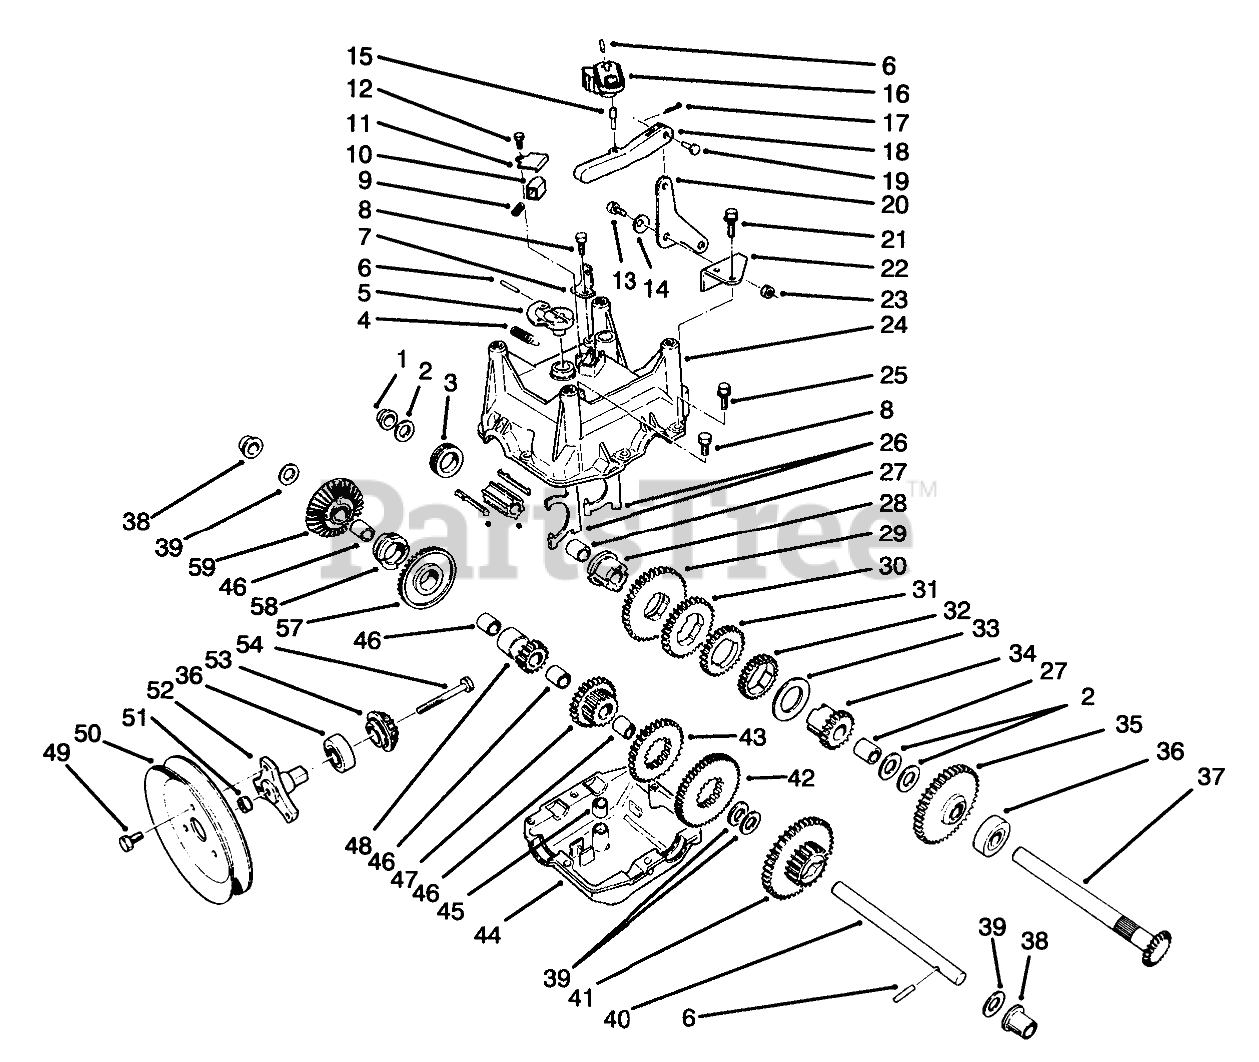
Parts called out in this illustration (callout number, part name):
1	BUSHING-FLANGE, OUTPUT
2	BEARING-THRUST
3	COLLAR-SHIFT
4	SPRING-EXTENSION
5	LEVER
6	PIN-SPRING
7	BRACKET-CABLE
8	SCREW-HWH
9	SPRING-DETENT
10	BUTTON-DETENT
11	COVER-DETENT
12	SCREW-HWH
13	SCREW-SHOULDER
14	WASHER-CURVED
15	PIN-LINK, GEAR SHIFT
16	LEVER-SHIFT, GEAR
17	PIN-COTTER
18	LINK-SHIFT, GEAR
19	PIN-CLEVIS
20	BELLCRANK
21	SCREW-HWH
22	BRACKET-BELLCRANK
23	NUT-LOCK, NI
24	GEARCASE-UPPER, CASING
25	SCREW-HWHTF
26	YOKE-SHIFT
27	BUSHING-OUTPUT
28	SLEEVE-GEAR
29	GEAR-45 T
30	GEAR-34 T
31	GEAR-27 T
32	GEAR-29 T
33	WASHER-THRUST
34	GEAR-SLEEVE, 19 T
35	GEAR-41 T
36	BEARING-BALL
37	SHAFT-OUTPUT
38	BUSHING-INTERMEDIATE
39	WASHER-THRUST
40	SHAFT-INTERMEDIATE
41	GEAR-19/41 T
42	GEAR-51 T
43	GEAR-33 T
44	GEARCASE-LOWER, CASING
45	BUSHING-YOKE
46	Bushing-Output
47	GEAR-26 T
48	GEAR-BEVEL, 15 T
49	SCREW
50	TRACTION-SHEAVE, HALF
51	NUT-HHF
52	HUB-PULLEY
53	PINION-BEVEL
54	SCREW-HH
55	SLEEVE-SHIFT
56	KEY-SHIFT
57	GEAR-BEVEL, 36 T
58	COLLAR-SHIFT
59	Gear-Bevel Reverse 36T (Incl. Ref. #46)
